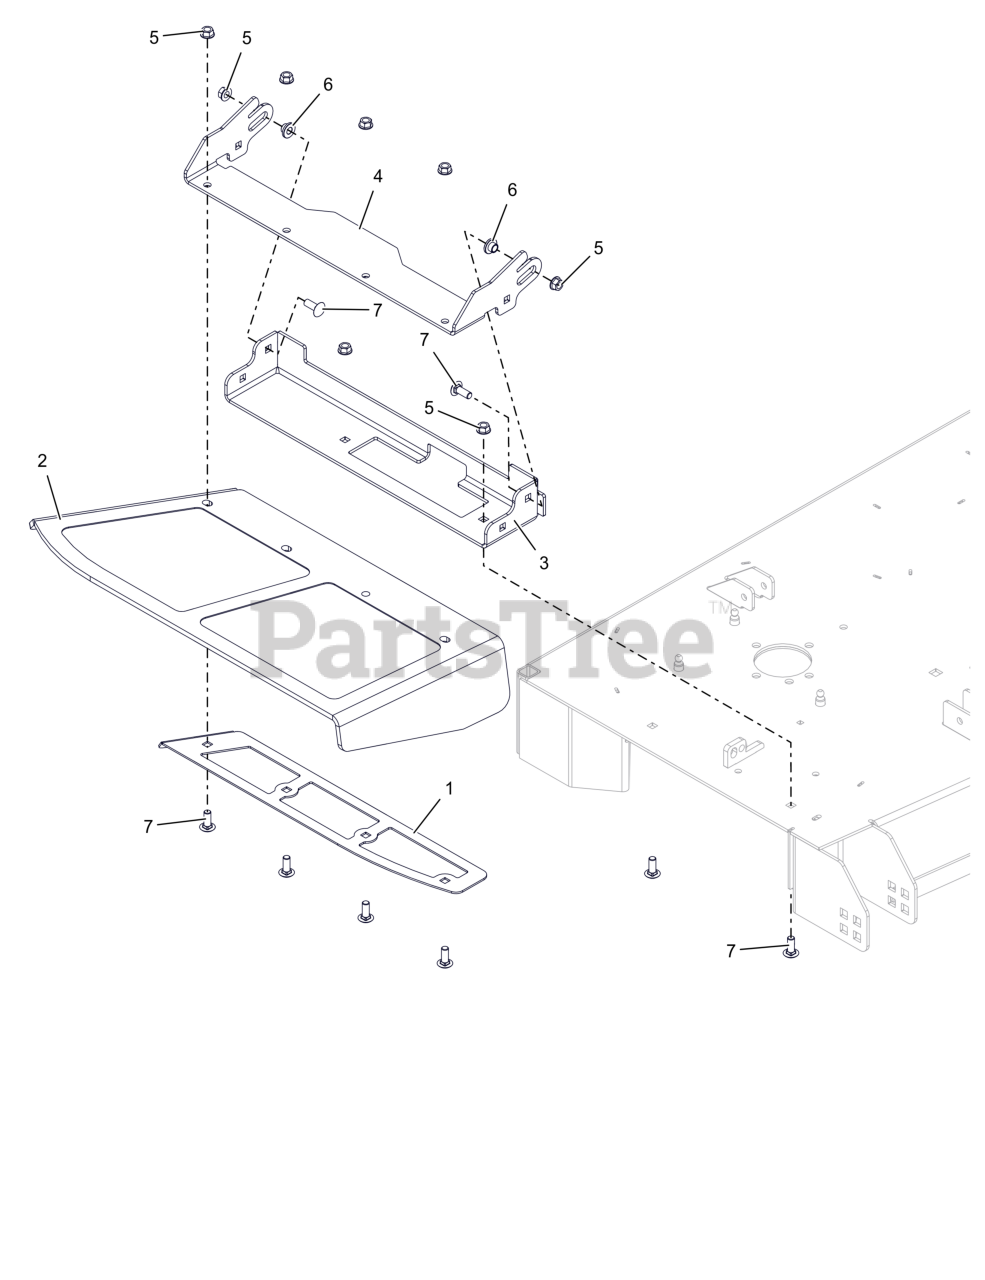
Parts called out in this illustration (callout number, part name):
1	DISCHARGE CHUTE CLAMP PLT -RED
2	CHUTE, FORMED RUBBER DISCH
3	BASE, DISCHARGE CHUTE MTG (RED) W/ SAFETY DECALS
4	BRKT, CHUTE MTG (RED)
5	NUT-LK-CTR-FLG .375-16 GF ZCC
6	BSHG-FLG .385X.500X.875X.406
7	BLT,RHSSN .38-16X1.00 G5 ZCC
